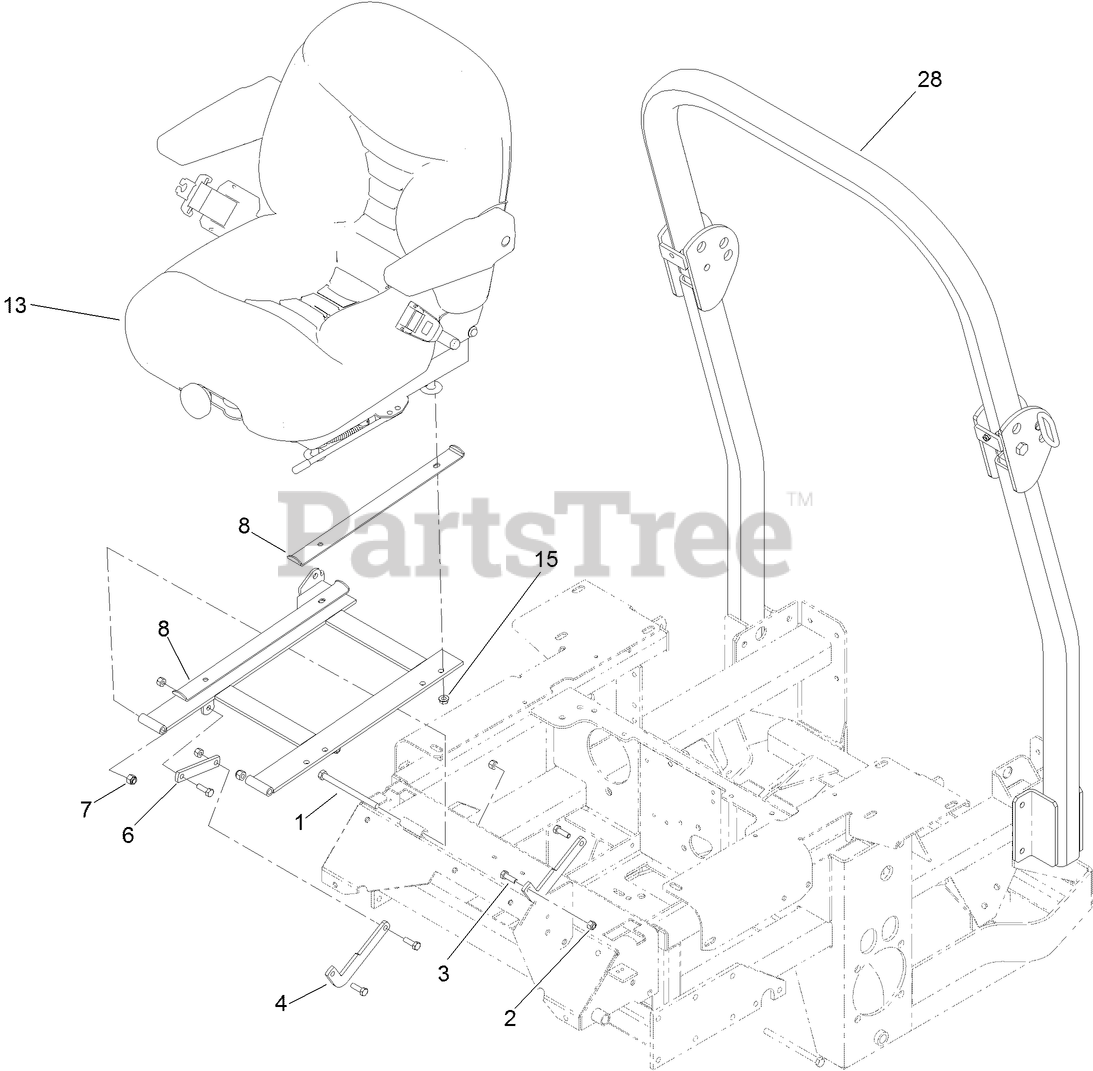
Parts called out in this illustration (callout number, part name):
1	SCREW-HH
2	NUT-LOCK, NI
3	SCREW-HH
4	LINK-STOP, SEAT
6	LINK-STOP, SEAT
7	NUT-LOCK, NI
8	STOP-SEAT
13	DELUXE SEAT ASM
15	NUT-HF
28	ROPS ASM
